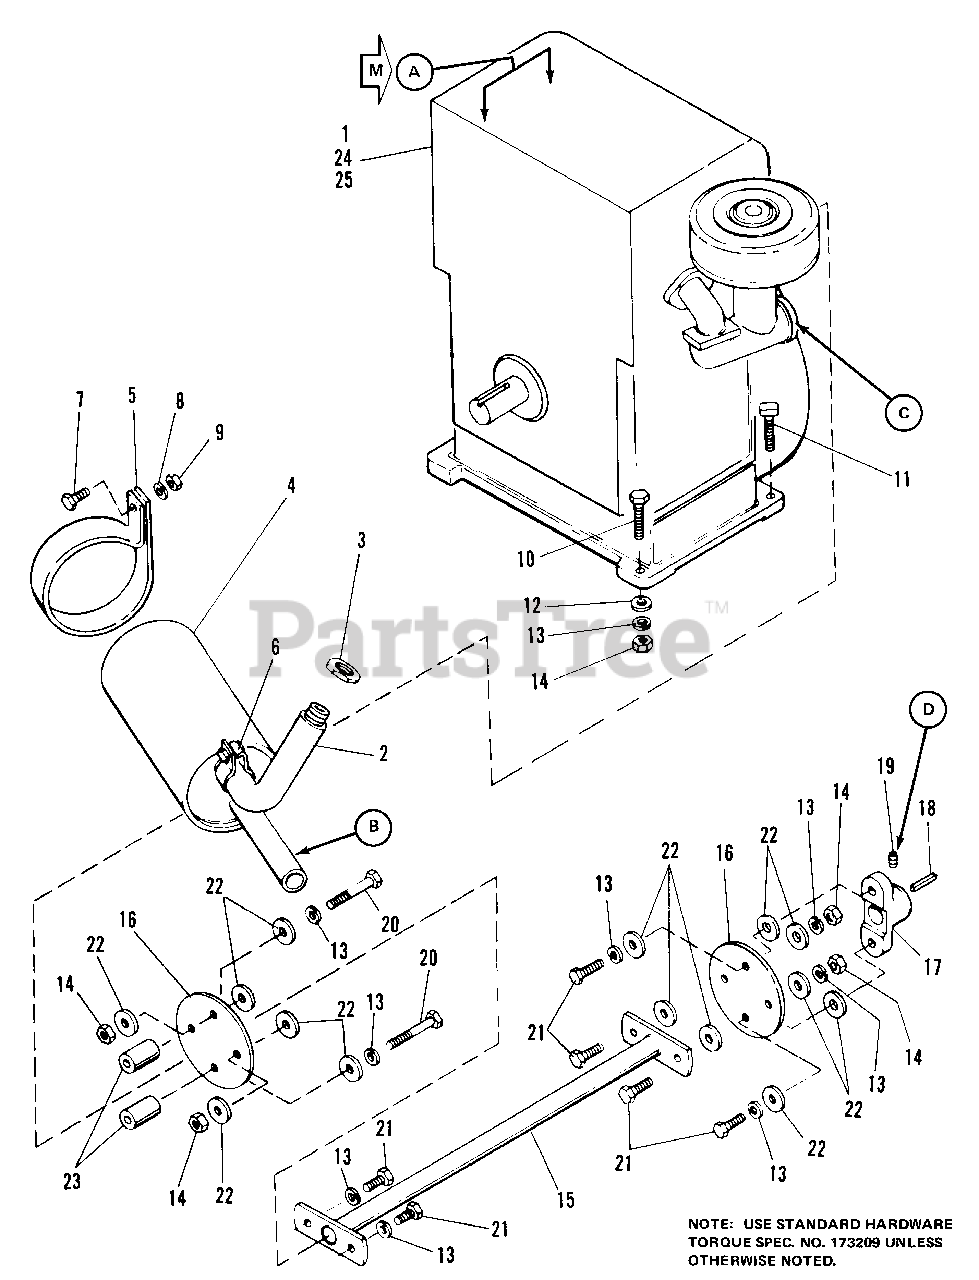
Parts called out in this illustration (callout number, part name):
1	ENGINE, 10 H.P.-Briggs & Stratton
2	ELBOW & NIPPLE ASSEMBLY
5	STRAP, Muffler
6	CLAMP, Muffler
7	CAPSCREW, Hex Hd., 5/16-18 x 1-1/2
8	LOCKWASHER, 5/16
9	NUT, Hex, 5/16-18
10	CAPSCREW, Hex Hd., 3/8-16 x 1-1/2
11	CAPSCREW, Hex Hd., 3/8-16 x 1-5/16
12	WASHER, 3/8
13	LOCKWASHER, 3/8
14	NUT, Hex, 3/8-16
15	DRIVESHAFT ASSEMBLY
17	FLANGE, DRIVESHAFT
18	KEY, Driveshaft
19	SETSCREW, 3/8-24 x 3/8
20	CAPSCREW, Hex Hd., 3/8-16 x 2-1/4
21	CAPSCREW, Hex Hd., 3/8-16 x 1-1/4
22	WASHER, Special
24	ENGINE, 16 H.P.-Briggs & Stratton
